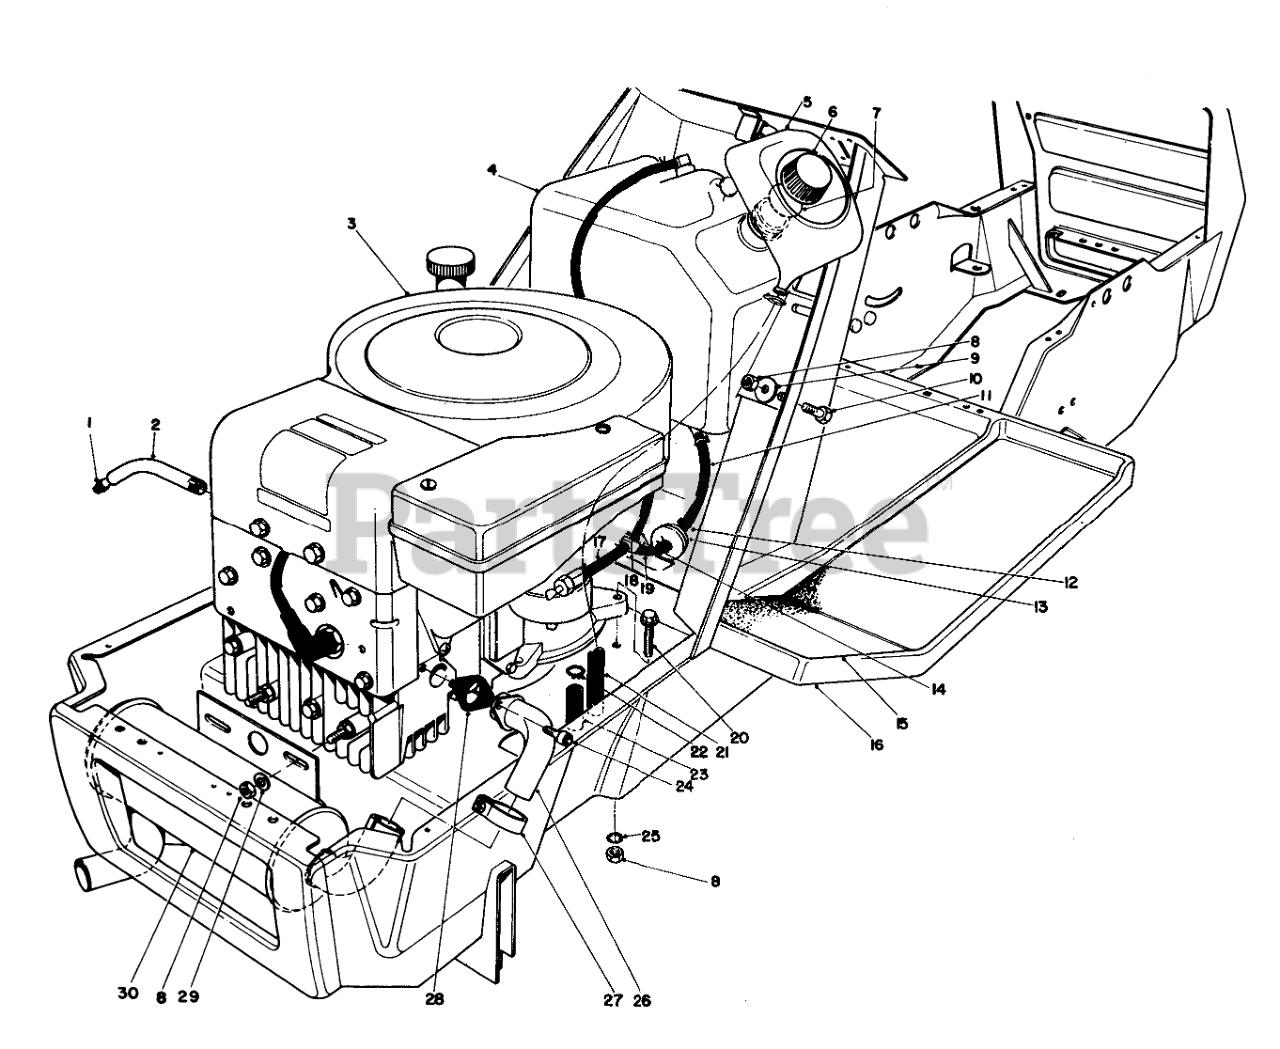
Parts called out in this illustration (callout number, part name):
1	PLUG-PIPE, SQH
2	OIL DRAIN TUBE
3	Engine
4	Gas Tank Assy. (Incl. Ref. #5)
5	Funnel-Overflow
6	Gas Cap Assy. (Incl. Ref. #7)
7	Gasket Gas Cap
8	NUT-LOCK, CONE
9	WASHER
10	SCREW-HH
11	GAS HOSE
12	Clamp
13	Nut
14	Hose Gas Return
15	LH FOOT TREAD
16	Frame
17	Hose Gas
18	Fitting-Barbed Y
19	Hose Gas
20	SCREW-HH
21	FUNNEL HOSE
22	HOSE CLAMP
23	CARB DRAIN HOSE
24	SCREW-HSH
25	WASHER-LOCK, INTERNAL
26	10 HP EXHAUST PIPE WA
27	MUFFLER CLAMP
28	Exhaust Gasket
29	WASHER-PLAIN
30	EXHAUST MUFFLER 10 HP
